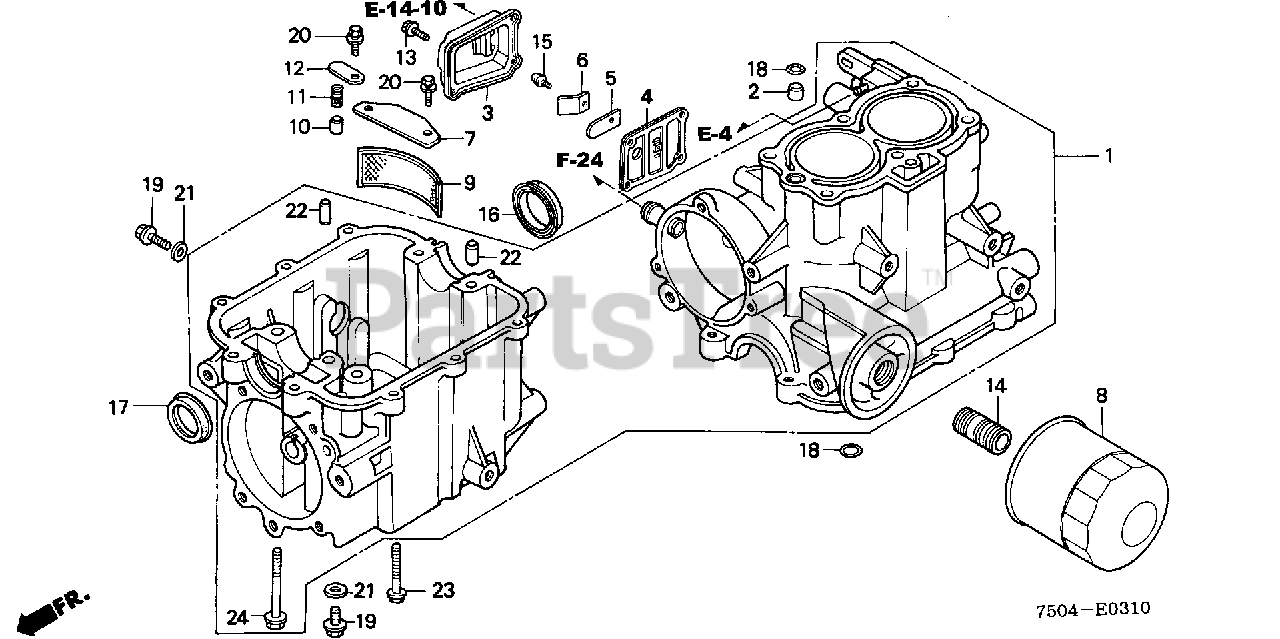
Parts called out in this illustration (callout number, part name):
1	CYLINDER ASSY.
2	ORIFICE, OIL CONTROL
3	COVER, BREATHER
4	PLATE, BREATHER
5	PLATE, VALVE
6	STOPPER, VALVE
7	PLATE, OIL FILTER
8	FILTER, OIL
9	SCREEN, OIL FILTER
10	VALVE, CHECK
11	SPRING, VALVE
12	PLATE, VALVE
13	BOLT, FLANGE (6X14)
14	PIPE, OIL PASSAGE
15	SCREW-WASHER (5X8)
16	OIL SEAL (33X48X7)
17	OIL SEAL (30X44X7)
18	O-RING (10.8X2.4) (ARAI)
19	BOLT, DRAIN PLUG (12MM)
20	BOLT-WASHER (6X12)
21	WASHER, DRAIN PLUG (12MM)
22	PIN A, DOWEL (10X16)
23	BOLT, FLANGE (6X28)
24	BOLT, FLANGE (8X55)
